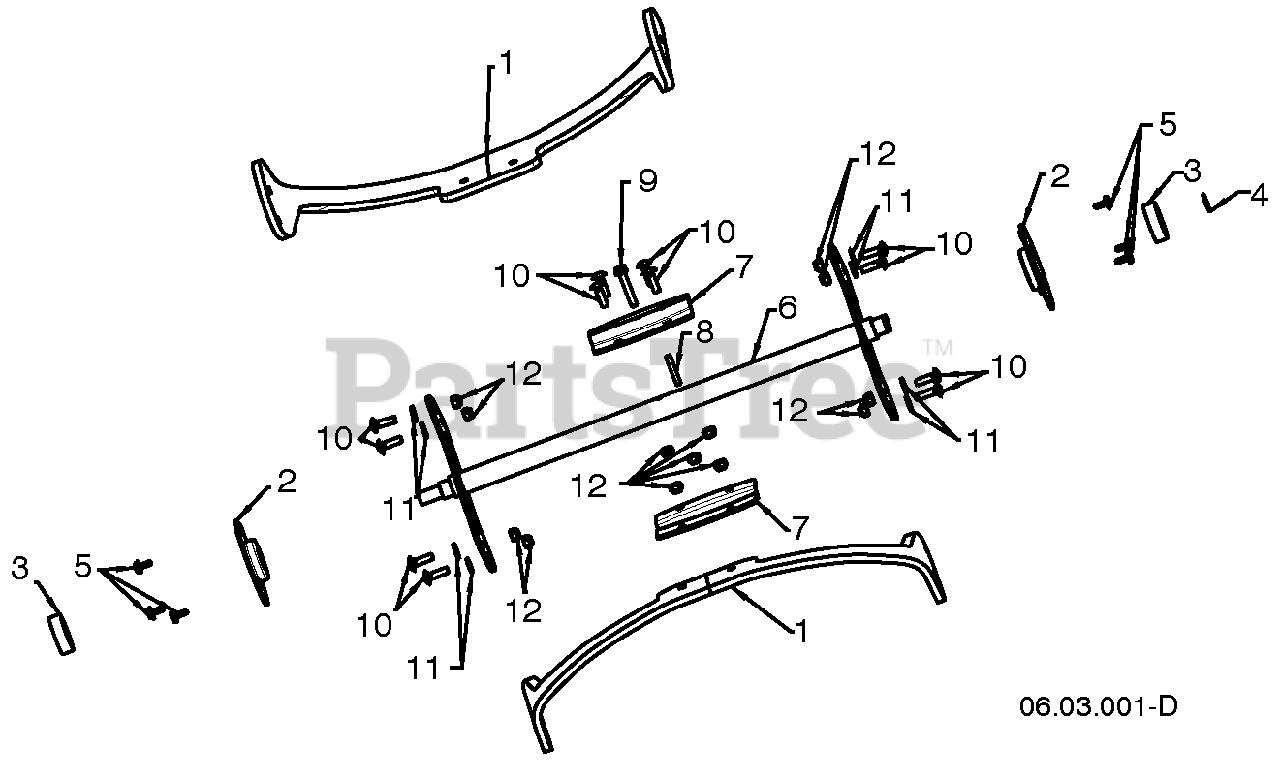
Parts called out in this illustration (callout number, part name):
1	AUGER.BLADE.SS.SNOW
2	SUPPORT.BEARING.SINGLE.STAGE.B
3	BEARING.BALL.MANDREL
4	RETAINING RING LT
6	WELDMENT.AUGER.SINGLE.STAGE.BL
7	PLATE.CENTER.BLADE.BLACK
8	PIN.ROLL.3/16 X 1-1/4
10	BOLT.CARRIAGE.1/4-20 X 7/8
11	WASHER
12	NUT
